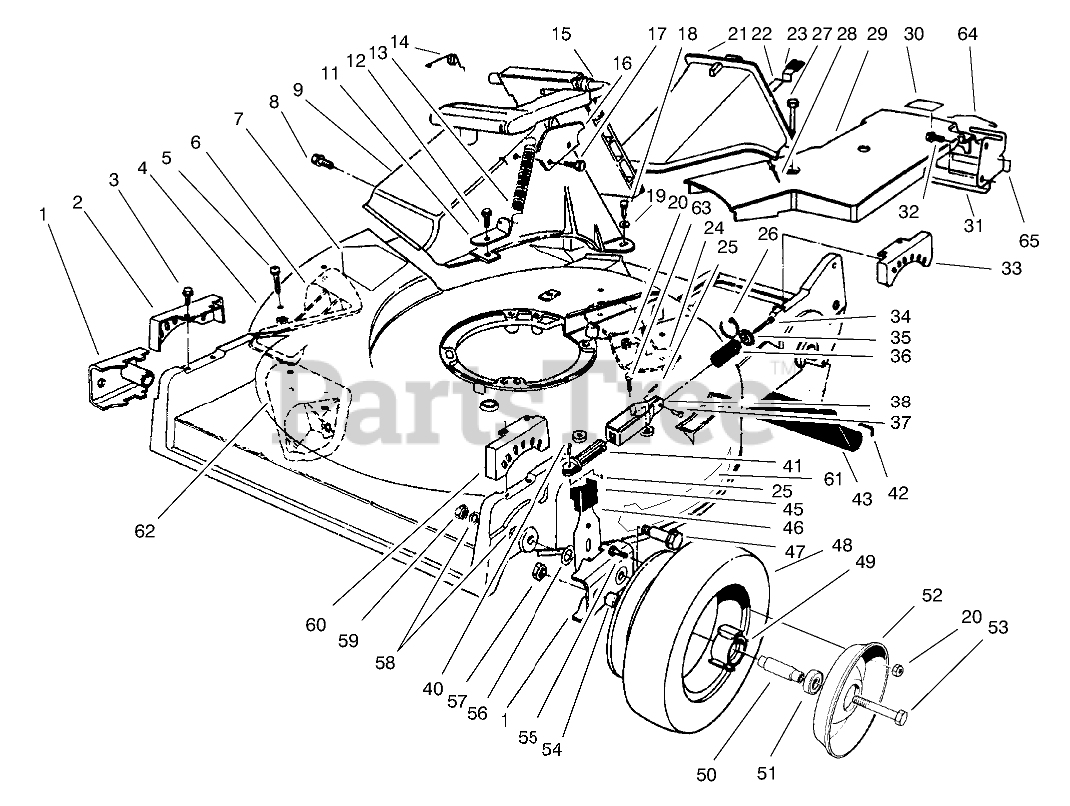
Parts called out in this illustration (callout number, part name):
1	ARM-PIVOT, FRONT
2	QUADRANT-FRONT, RH
3	SCREW-HWHTF
4	Housing-Commercial (Incl. Ref. #5-7, 24, & 62) (Incl. Ref. #28 pg. 4)
5	SCREW-PPH
6	KICKER-RH
7	DECAL-DANGER
8	SCREW AND WASHER ASM
9	TUNNEL-DISCHARGE
11	BRACKET-SPRING
12	SCREW-HWH
13	SPRING-DOOR
14	RETAINER-DOOR
15	DISCHARGE DOOR ASM
16	LATCH-PLATE
17	SCREW-PLASTITE
18	SCREW-HH
19	WASHER-FLAT
20	NUT-LOCK, NI
21	Plug-Discharge (Incl. Ref. #22, 23, & 28)
22	LATCH-PLUG, DISCHARGE
23	GRIP-LATCH
24	KICKER-REAR
25	PIN-COTTER
26	TIE-CABLE
27	SCREW-HHFTF
28	RIVET-HEAD, FLAT
29	BELT COVER
30	LABEL-GREASE
31	BRACKET-ADJUSTMENT, TRACTION
32	SCREW-HWHTF
33	QUADRANT-REAR, LH
34	SCREW-HWHTF
35	RETAINER-SPRING
36	SPRING
37	PIN-CABLE
38	Bracket-Spring
40	PIN-SPRING
41	GUIDE-SPRING
42	ROD-SHIELD
43	SHIELD-TRAILING
45	KNOB-ARM
46	FRONT SPRING ARM ASM
47	BOLT-WHEEL
49	HUB-BEARING
50	SPACER-BEARING
51	BEARING-WHEEL
52	Wheel-Half
53	SCREW-HH
54	SPACER-WHEEL
55	SCREW-HH
56	WASHER-THRUST
57	NUT-LOCK, CONE
58	WASHER
59	NUT-LOCK
60	QUADRANT-FRONT, LH
61	DECAL-RECYCLER
62	KICKER-FRONT
63	SCREW-HH
64	RETAINER-CABLE
65	DECAL-POSITION, GEAR
